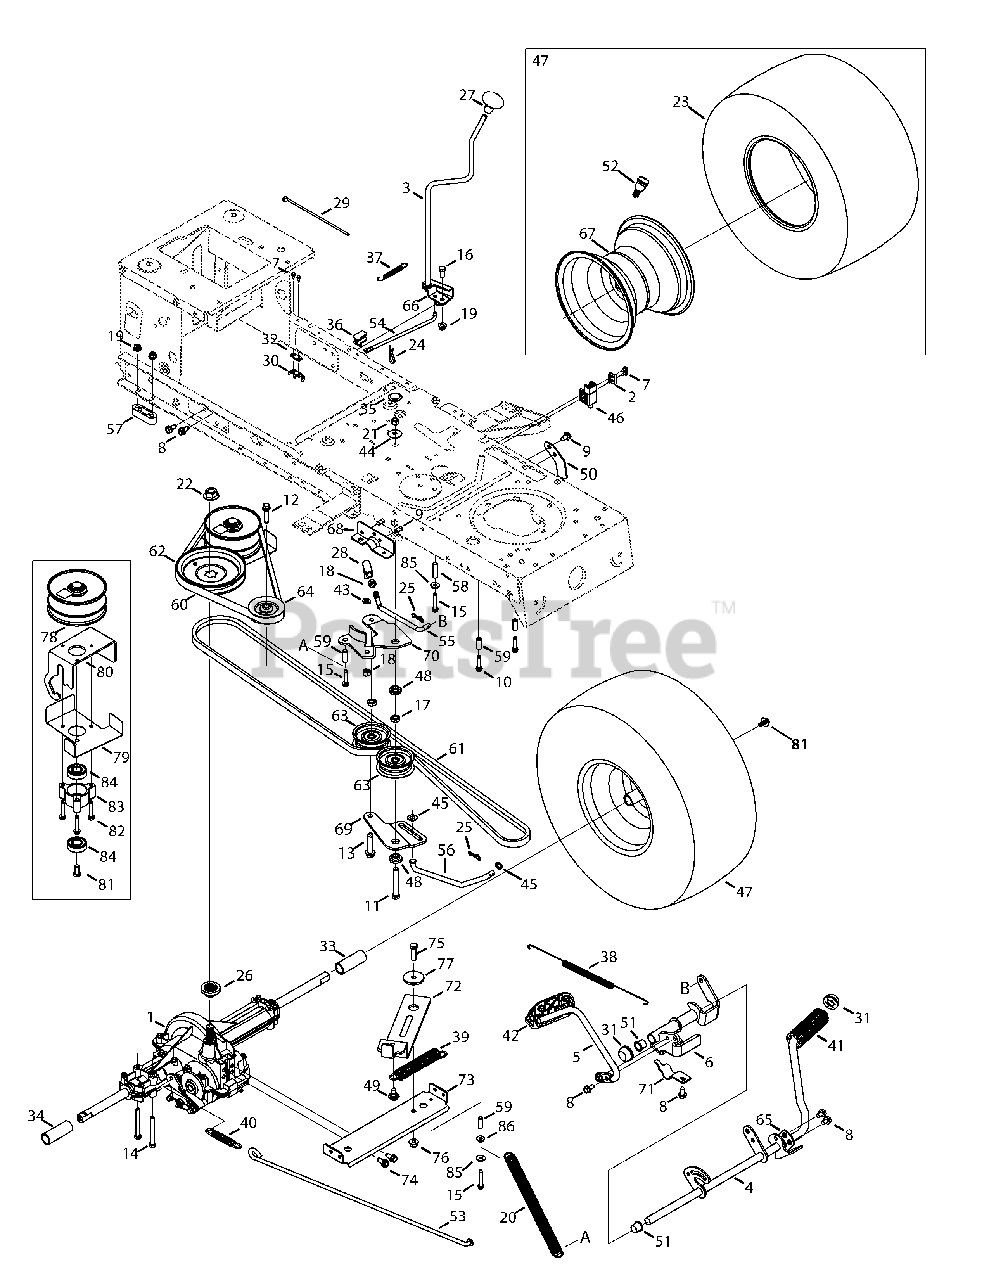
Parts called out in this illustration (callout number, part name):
1	Transmission Drive Assembly
2	Plate Switch
3	Shaft Lever Assembly
5	Pedal Assembly, control
6	Pedal Bracket Assembly
7	Screw, 8-18:0.500
8	Screw, 5/16-18 x .750
9	Screw, 5/16-18 x 0.625
10	Screw, 1/4-20 x 1.250
11	Hex Screw, 3/8-16 x 2.50
12	Screw, 3/8-16 x 1.500
13	Screw, 3/8-16 x 1.750
14	Hex Screw, 5/16-18 x .625
15	Screw, 1/4-20 x 1.75
16	Hex Screw, 5/16-18 x .75
17	Jam Nut, 7/16-20
18	Hex Nut, 3/8-24
19	Flangelock Nut, 5/16-18
20	Spring Extension, 1.0 OD x 11.125
21	Nut, 3/8-16, Centerlock
22	Flange Nut, 9/16-18
23	Tire, 20 X 8 X 8 Sq Shldr
24	Cotter Pin INT- .125 DIA
25	Bow-Tie Cotter Pin, 72
26	Pulley Hub, 5/8 SPLINE
27	Shift Knob
28	Ball joint
29	Cable tie
30	Short Spring Switch
31	Push Cap, 5/8
32	Plate Insulator Nut
33	Sleeve, .758 x .821 x 3.3125
34	Sleeve, .758 x .821 x 2.4375
35	Plug, 7/8
36	Shift Plate Bearing
37	Spring Extension, .38 OD x 3.25 LG
38	Spring Extension, .70 OD X 12.00
39	Spring Extension, .97 Od X 6.18 Lg
40	Spring Extension, .59 OD x 4.00 LG
41	Foot Pad, 4.0 Long
42	Control Pad
43	Lock Washer 3/8
44	Flat Washer, .406 x 1.920 x .060
45	Flat Washer, .375 X .738 X .063
46	Switch Interlock
47	Wheel, 20 x 8 x 8 - Grey
48	Shoulder Spacer, 1.00 X .38 X .38
49	Shoulder Screw, .43 x .29, 5/16-18
50	Stop Pedal Plate
51	Flng Bearing .63 Id x .695 Od X .60
52	Valve, tubeless Air
53	Brake Rod
54	Shift Rod, 46"
55	Idler Adjustment Rod
56	Transmission Bypass Rod
57	Spacer, T-Axle .68
58	Spacer, .260 X .372 X 1.420 Lg
59	Spacer, .260 X .375 X 1.030 Lg
60	V Belt, 5L 40.9 Poly
61	V Belt, 5L, 90.93 Poly
62	V Pulley 7.25 DIA SPUN
63	Idler Pulley
64	Idler Pulley
65	Pedal Support Bracket
66	Shaft Adjust Bracket
67	Rim, 8.0 X 7.0 X .750
68	Frame Pedal Bracket, Rh
69	Center Idler Bracket
70	Idler Bracket
71	Pedal Support Bracket
72	Idler Bracket Assembly
73	Bracket Assembly
74	Screw, 5/16-18 x 0.750
75	Hex Screw, 3/8-16 x 1.25
76	Flangelock Nut, 3/8-16
77	Shoulder Spacer, .8840 X .190
78	Variable Speed Pulley Assembly
79	Belt Keepr Assembly
80	Bracket Assembly
81	Screw, 5/16-24 x .750
82	Screw, 1/4-20 x 1.500
83	Bearing Cup
84	Ball Bearing, 17 x 40 x 12
85	Flat Washer, .260 x .720 x .060
86	Shoulder Spacer, .375 x .625 x .20
